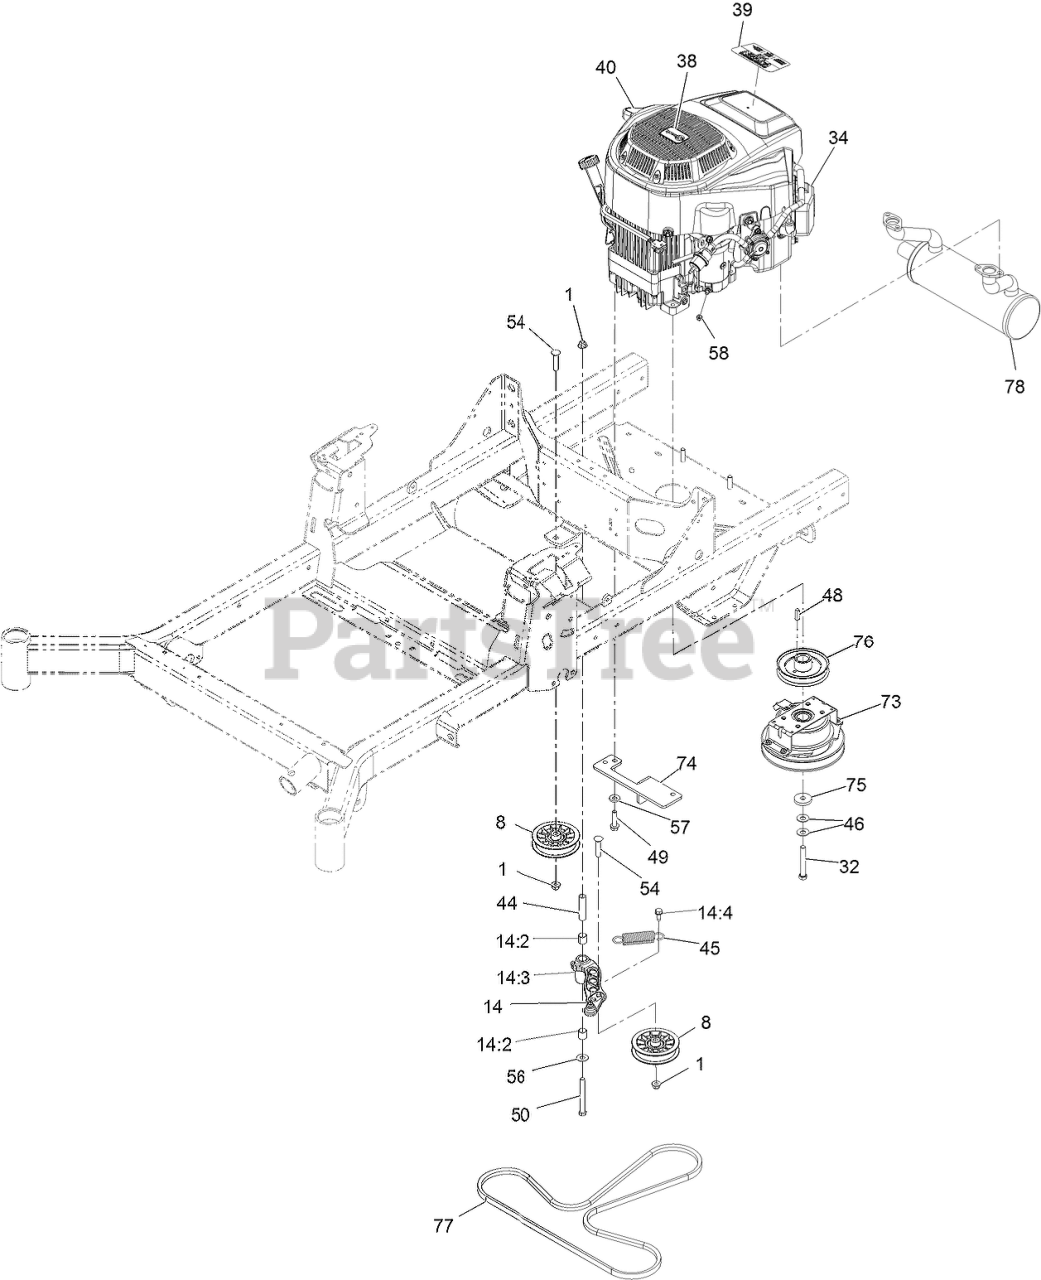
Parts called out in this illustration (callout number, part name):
1	NUT-HF, NI
8	PULLEY-FLAT IDLER
14	IDLER ARM ASM
14:2	SLEEVE-BEARING
14:3	FITTING-GREASE, 90 DEG
14:4	SCREW-THD ROLL, HWH
32	SCREW-HH W/LOCTITE
34	ENGINE-2P77F
39	DECAL-ENGINE 708 V-TWIN EXMARK
40	DECAL-DRAIN, OIL
44	BUSHING-PIVOT, IDLER
45	SPRING-EXTENSION
46	WASHER-SPRING
49	SCREW-HWH
50	SCREW-HH
54	SCREW-CARR
56	WASHER-FLAT
57	WASHER-BELLEVILLE
73	Clutch 1.00
74	ANCHOR CLUTCH
75	WASHER-CLUTCH
76	Sheave-Engine
77	V-BELT
78	MUFFLER
